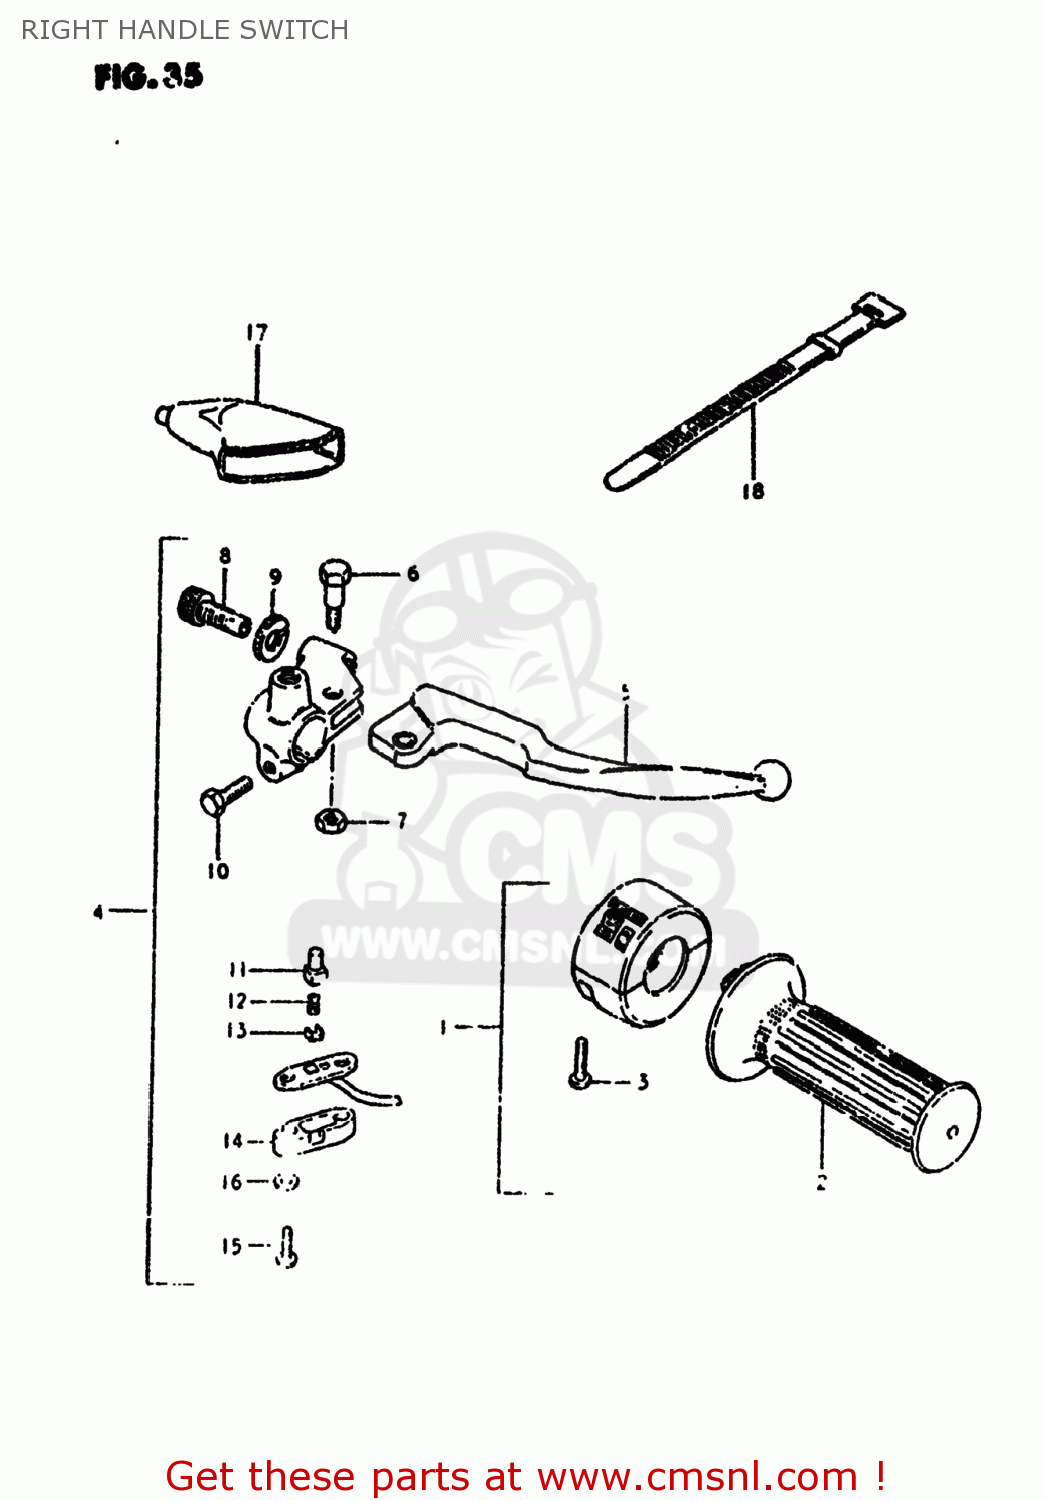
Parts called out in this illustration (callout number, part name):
1	CASE ASSEMBLY,THROTTLE
2	GRIP,THROTTLE
3	SCREW
4	LEVER/SWITCH ASSEMBLY,BRAKE
5	LEVER,BRAKE
6	BOLT,LEVER
7	NUT 6MM
8	BOLT
9	ADJUSTER,CABLE
10	NUT,CABLE ADJUSTER
11	HOLDER
12	SPRING
13	PLATE
14	COVER,FR BK TERMINAL BASE
15	SCREW
16	WASHER
17	COVER,CLUTCH LEVER
18	CLAMP(L:120)
